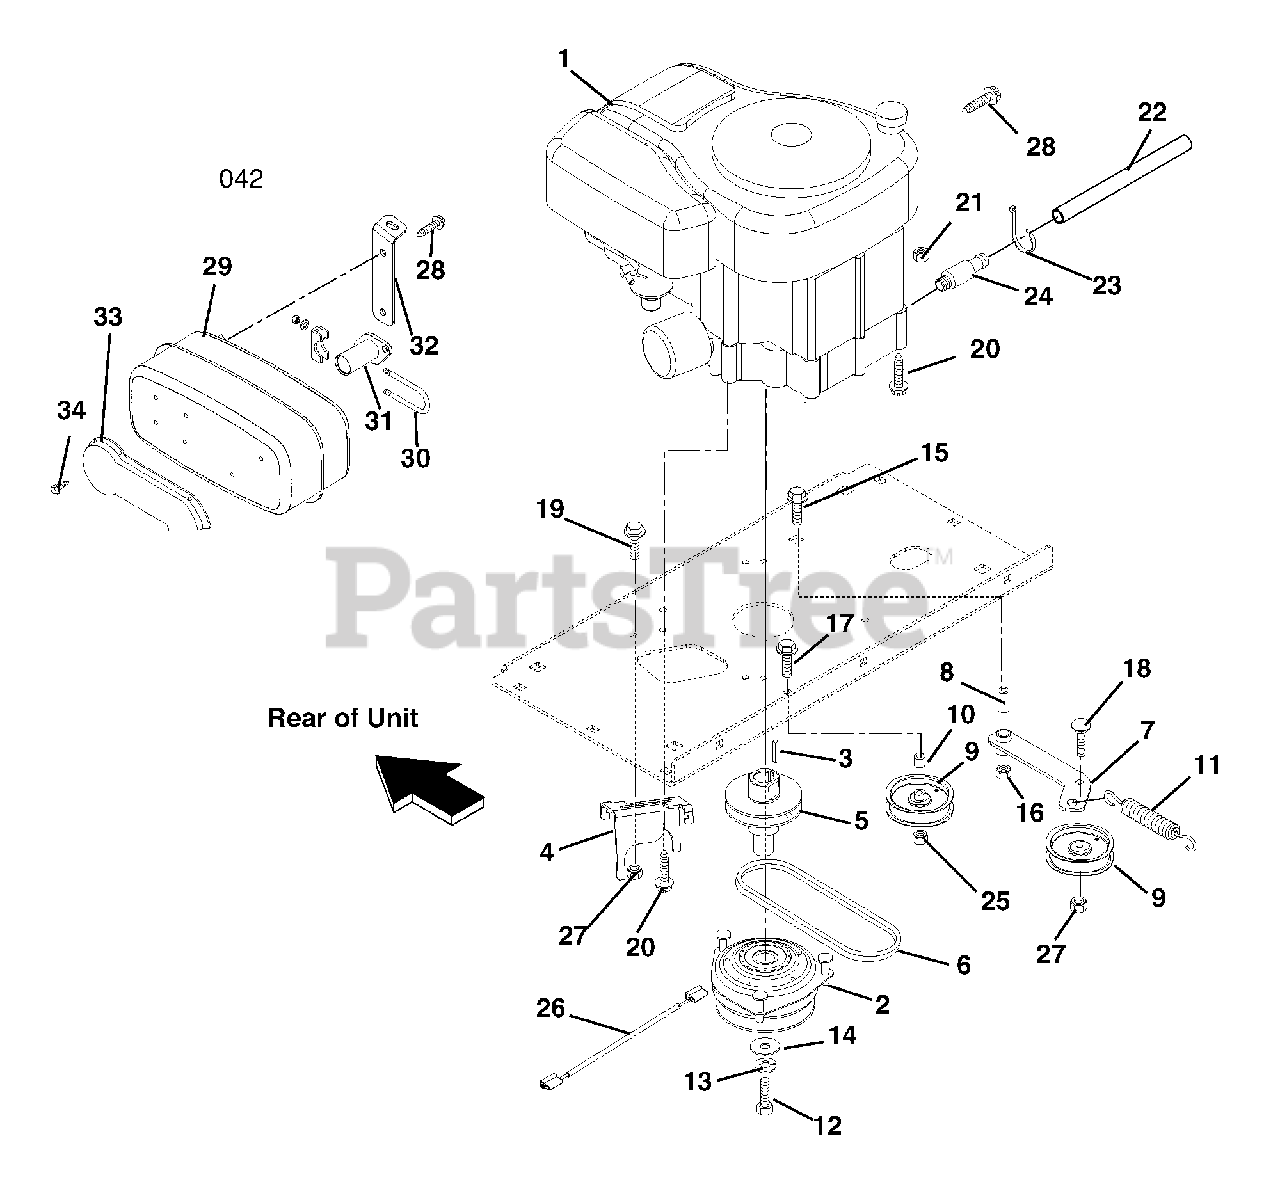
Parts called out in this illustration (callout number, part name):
1	Engine, 15HP Kohler
2	Clutch/Brake, Electric
3	Key, Square .25 x 1.50 x .25 SAE 8630 OR SAE 1035
4	Clutch Stop
5	Extension Shaft
6	V-Belt A-Section 25.1 x .495
7	Weldment, Idler
8	Bushing, Sleeve .50 x .75 x 1.56
9	Pulley, Idler 4.00
11	Spring, Extension
12	Bolt, Hex .44-20 x 4.50 Grade 8
13	Washer, Locking .44 x .109 Regular
14	Washer, Flat Steel .469 x 2.00 x .25
15	Bolt, Round Head Square Neck .50-13 x 2.50 Grade 5
16	Nut, Locking Top Flange .50-13
17	Bolt, Round Head Square Neck .38-16 x 2.00 Grade 5
18	Bolt, Round Head Square Neck .38-16 x 1.25 Grade 5
19	Bolt, Hex .38-16 x 1.00 Grade 5
20	Screw, Tapping .38-16 x 1.00 Hex Washer Head
21	Nut 5/16-18 Flange Nyloc
22	Tube, Oil Drain
23	Cable Tie
24	Valve, Oil Drain
25	Nut, Locking, Jam, Center .375-16
26	Adapter, Clutch Harness
27	Nut, .38-16 Flange Nyloc
28	Screw, Tapping .25-20 x .50 Hex Washer Head
29	Muffler, Kohler Courage Single
30	Clamp, Muffler
31	Weldment, Manifold
32	Bracket, Muffler
33	Deflector
34	Screw, Tapping 8-32 x .38 Slotted Hex Washer Head
